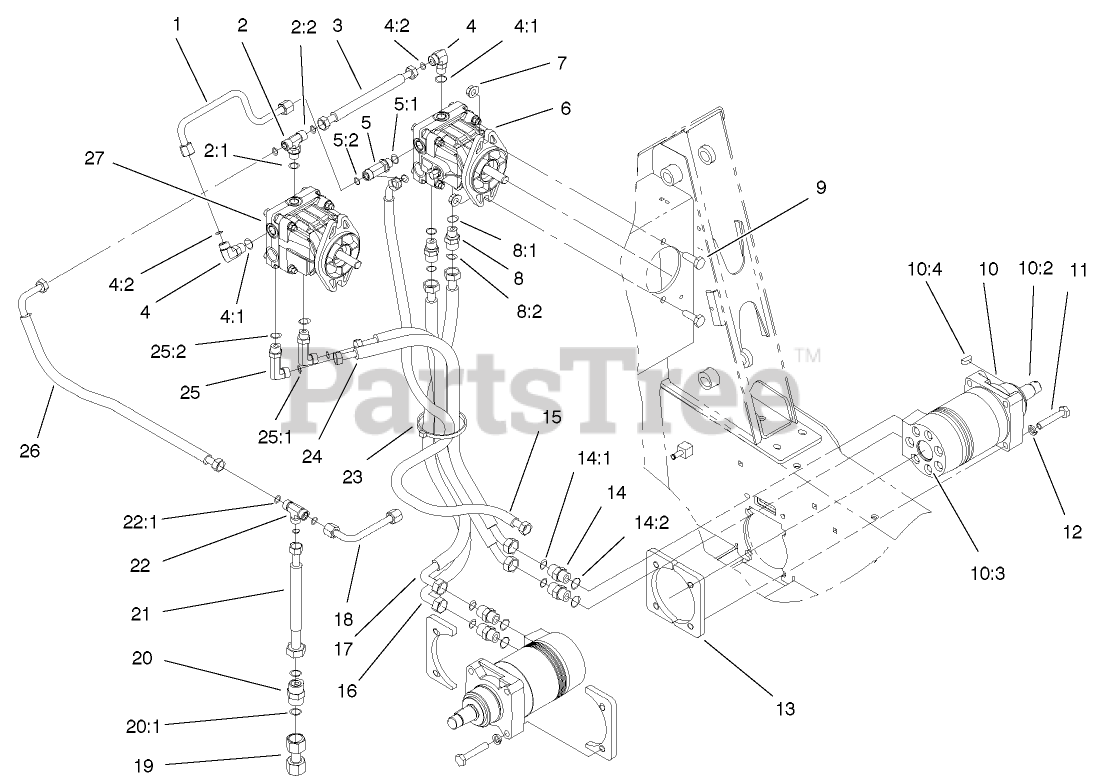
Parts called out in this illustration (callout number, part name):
1	TUBE-HYD
2	FITTING-HYD, TEE
2:1	O-RING
2:2	O-RING
3	HYD HOSE ASM
4	FITTING-ELBOW-90 DEG
4:1	O-RING
4:2	O-RING
5	FITTING-TEE
5:1	O-RING
5:2	O-RING
6	PUMP-HYD, LH
7	NUT-HF
8	FITTING-STR
8:1	O-RING
8:2	O-RING
9	SCREW-HH
10	MOTOR-WHEEL, HYD
10:2	SHAFT-COUPLING
10:3	SCREW-HH
10:4	KEY-WOODRUFF
11	SCREW-HH
12	WASHER-LOCK
13	PLATE-MOUNTING
14	FITTING-STRAIGHT
14:1	O-RING
14:2	O-RING
15	HOSE-HYD
16	HYD HOSE ASM
17	HYD HOSE ASM
18	HYD TUBE ASM
19	HYD TUBE ASM
20	HYD CHECK VALVE ASM
20:1	O-RING
21	HYD HOSE ASM
22	ADAPTER
22:1	O-RING
23	TIE-CABLE
24	HOSE-HYD
25	FITTING-ELBOW, 90 DEG
25:1	O-RING
25:2	O-RING
26	HYD HOSE ASM
27	PUMP-HYD, RH
